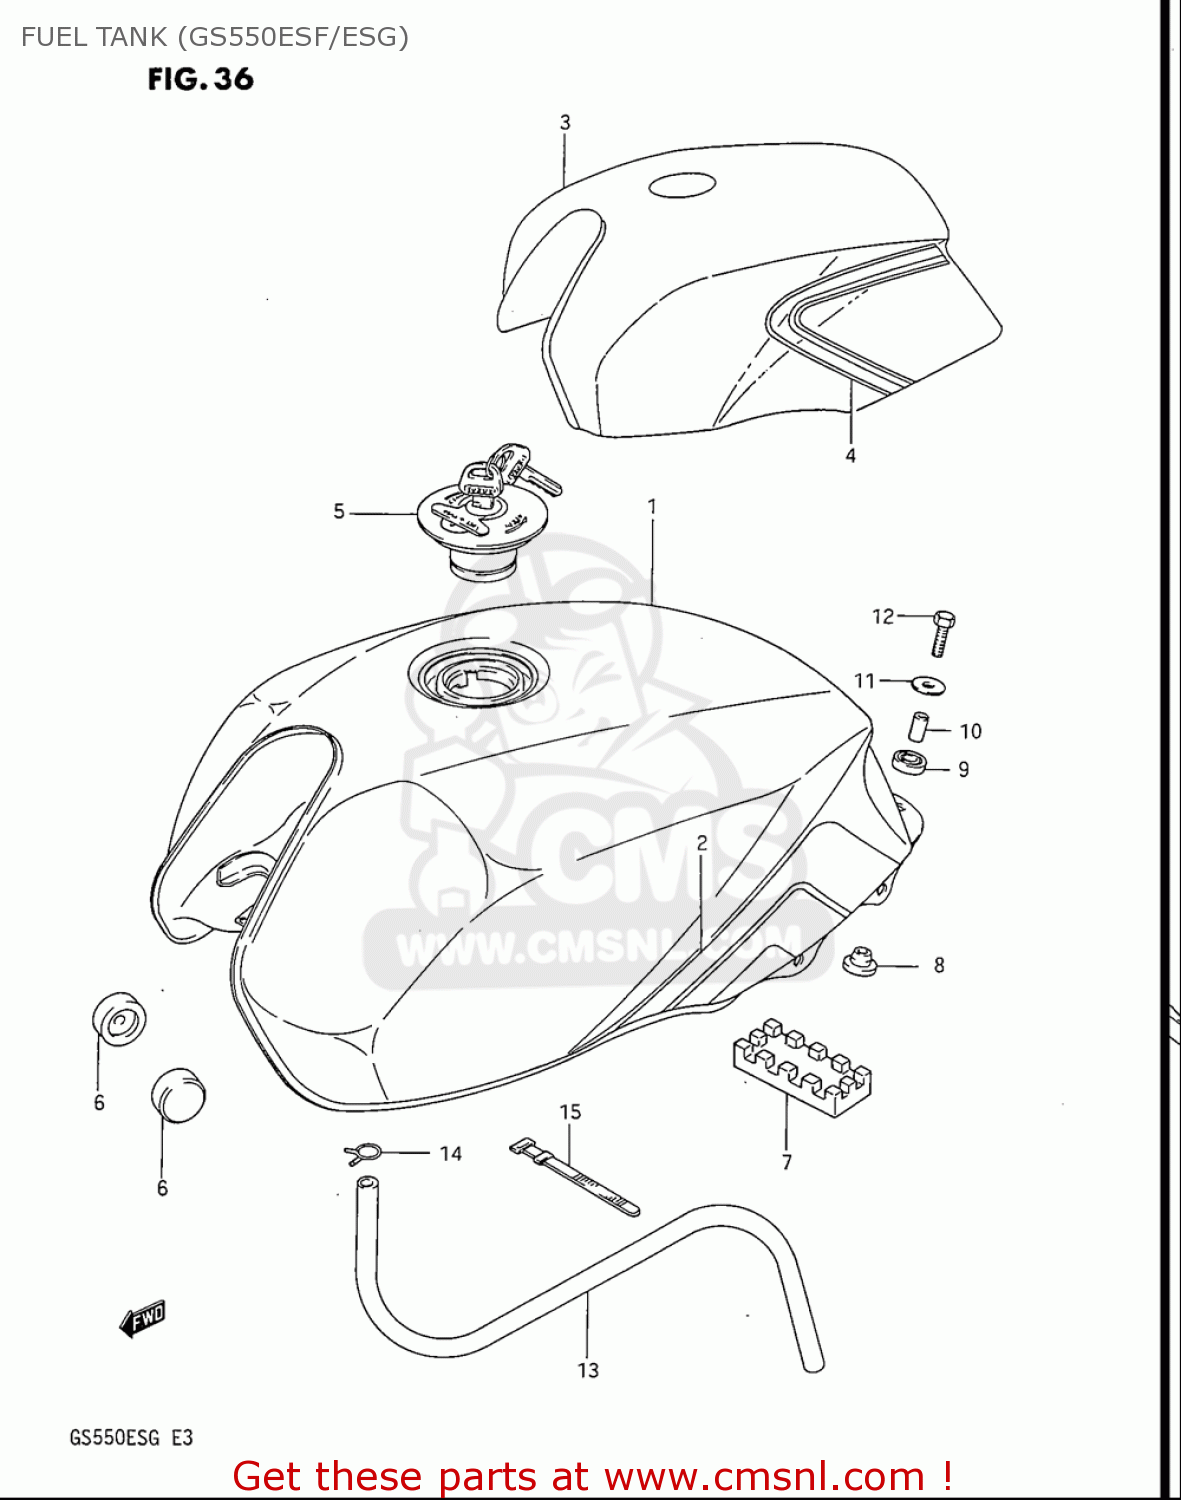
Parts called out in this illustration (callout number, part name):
1	TANK ASSEMBLY,FUEL
3	TANK ASSEMBLY,FUEL
5	CAP SET,FUEL TANK
6	CUSHION
8	CUSHION
9	CUSHION
10	SPACER(6.5X9X20)
11	WASHER(6.5X24X1.6)
12	BOLT
13	HOSE(5X8.2X2000)
14	CLIP
15	CLAMP(L:187)
